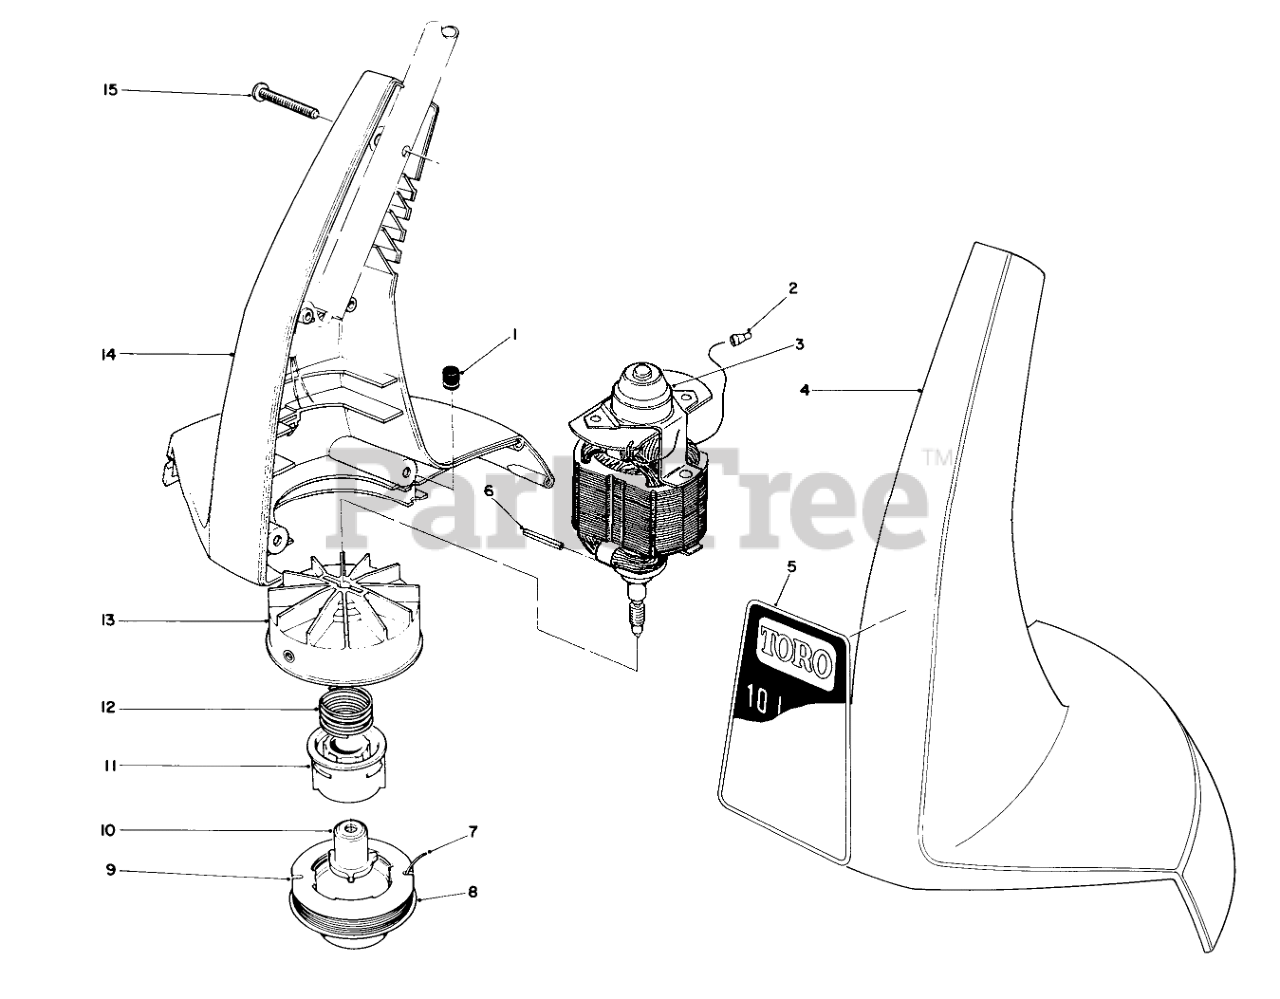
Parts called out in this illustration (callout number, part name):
1	GROMMET
2	CONNECTOR WIRE JOINT
3	Motor
4	Housing-L.H.
5	DECAL, 10" TRIMMER
6	COIL PIN
7	Cutting Line (30- .05 Dia.)
8	SPOOL CAP
9	Prewound Spool Cap
10	DRIVER DETENT
11	CORE - SPOOL
12	SPRING-COMPRESSION
13	FAN HUB ASM
14	Housing Assembly-R.H. (Incl. Ref. #16 & 17)
15	Capscrew
16	Rivet
17	Blade-Knife
